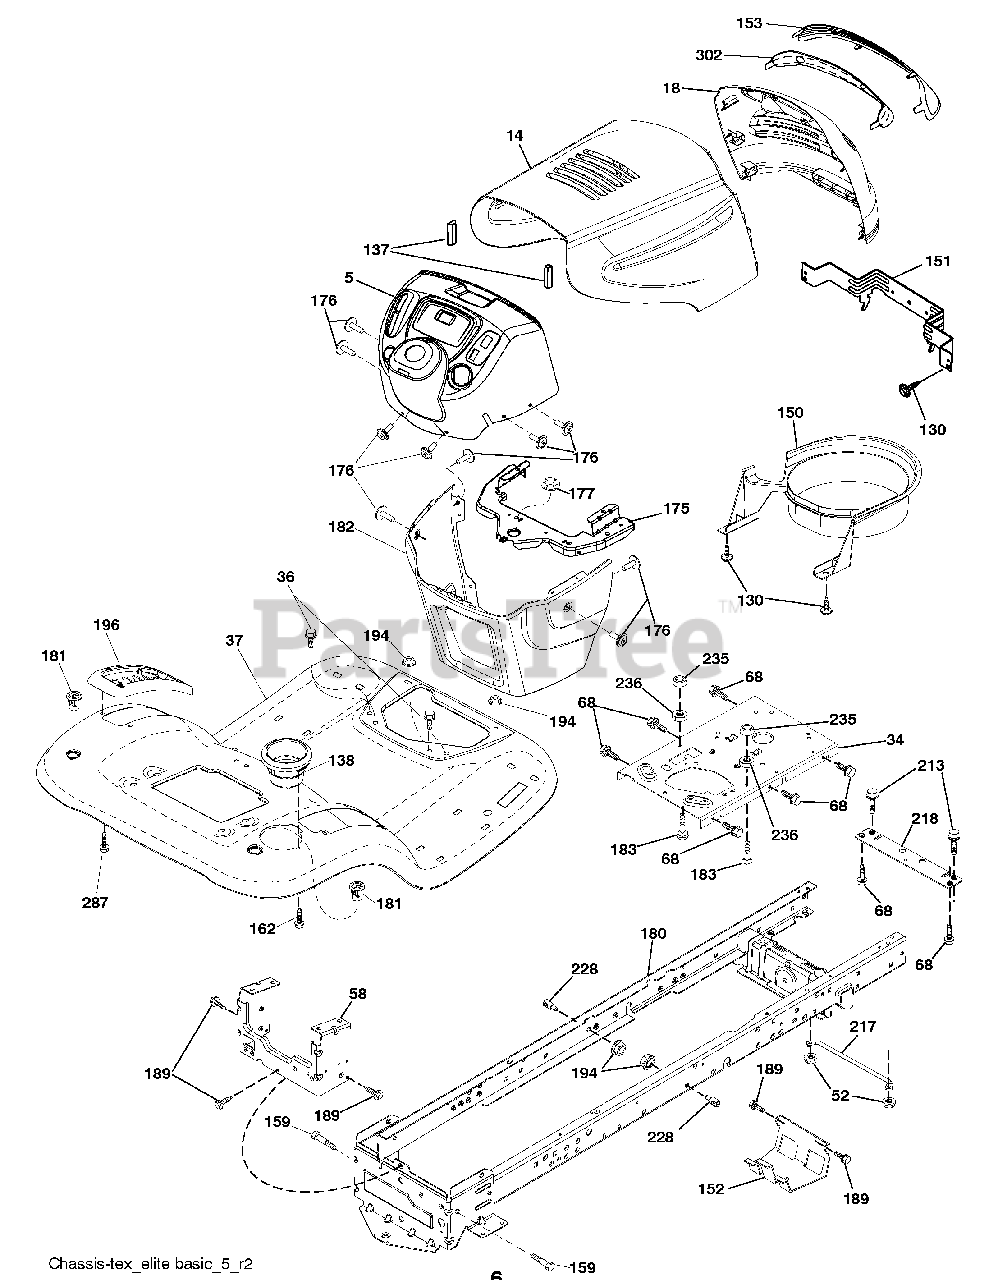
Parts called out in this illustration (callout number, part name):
5	Dash
18	Grille
34	Plate Engine
36	Screw 5/16-18 x 3/4
52	Nut Lock 5/16-18
58	Drawbar Upper
68	Screw Thdrol 5/16-18 x 1/2
130	Screw #10 x 0.750
137	Bumper Hood
138	Cupholder
150	Duct Heat Hood
151	Bracket Pivot
152	Shield Browning
153	Lens Grille
159	Screw Hexwsh Thdrol 3/8-16 x 3/4
162	Screw Hex Wsh Hi-Lo 1/4 x 1/2
175	Crossmember
176	Screw 10-24 x 5/8 Wshd Qdrx
177	Bushing Steering
180	Chassis
181	Bushing Mtg. Fender Crgo.
182	Dash Lower
183	Bolt 5/16-18 x 1-1/4
189	Screw 5/16-18 x 3/4
194	Nut Lock Hex Flange 5/16-18
196	Console Asm. Deck Lift
213	Bolt 5/16-18 x 3/4
217	Rod Pivot Hood
218	X-Piece Hood Step
228	Stud Fastener
235	Spacer Fender
236	Nut Center Lock 5/16-18
287	Screw 1/4-20 x 3/8
302	Insert Lens Reflective
